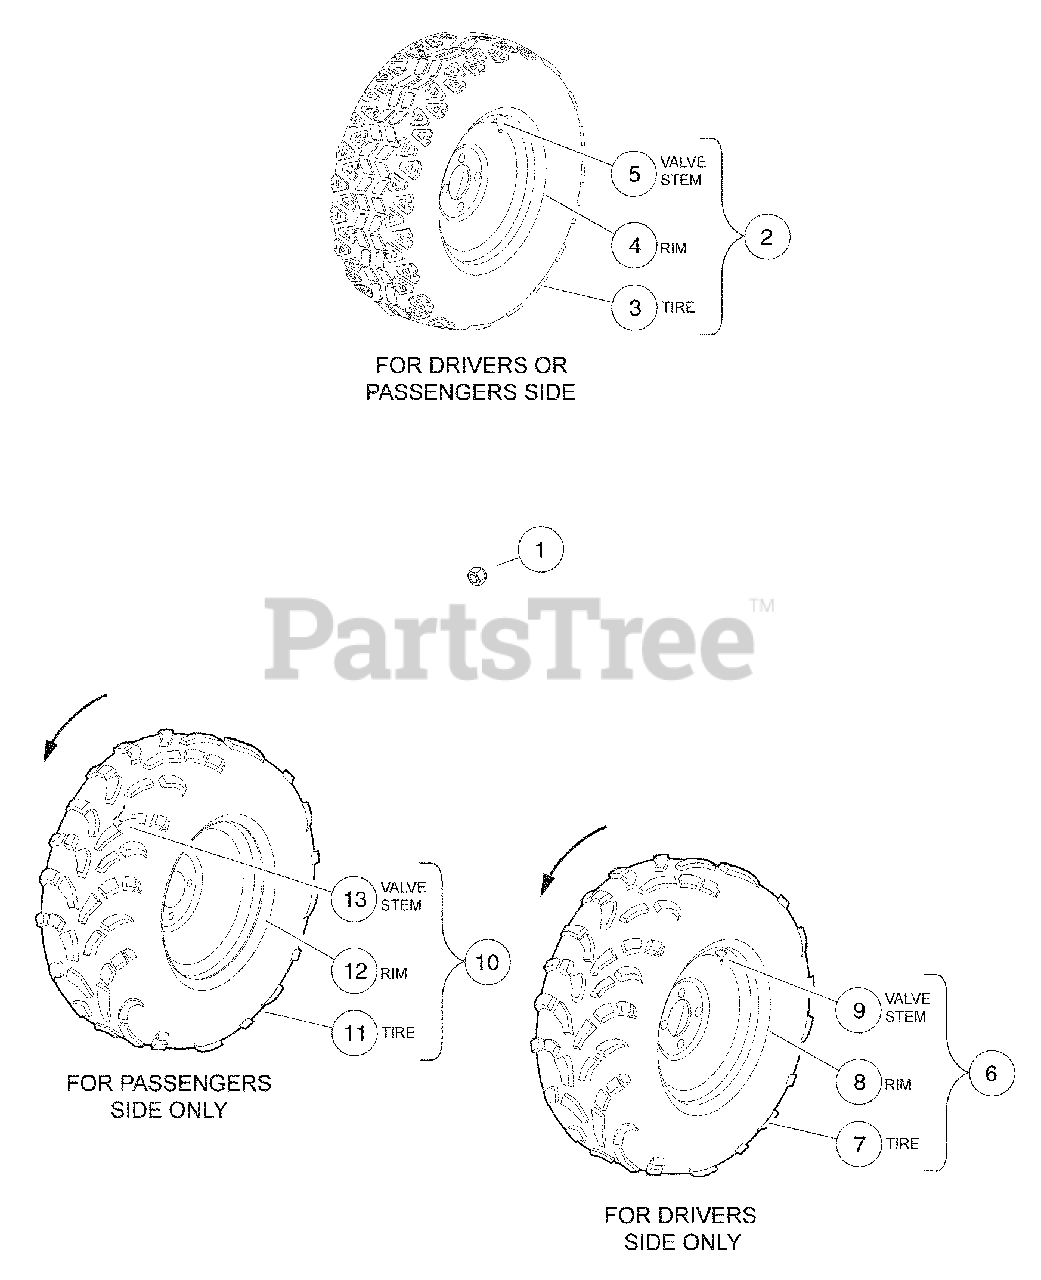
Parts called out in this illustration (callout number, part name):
1	Nut, Lug, 1/2-20 SAE J2283
2	Black Tire Asm HDAT 10.5 In
3	Heavy Duty All Terrain Tire, 25"
4	Wheel, All trail, 10 Win, Black
5	Valve Stem
6	Black Tire Asm Mud 11.0 In Left-Hand
7	Mud Tire, 25".
8	Wheel, All trail, 10 Win, Black.
9	Valve Stem
10	Black Tire Asm Mud 11.0 In Right-Hand
11	Mud Tire, 25".
12	Wheel, All trail, 10 Win, Black
13	Valve Stem
